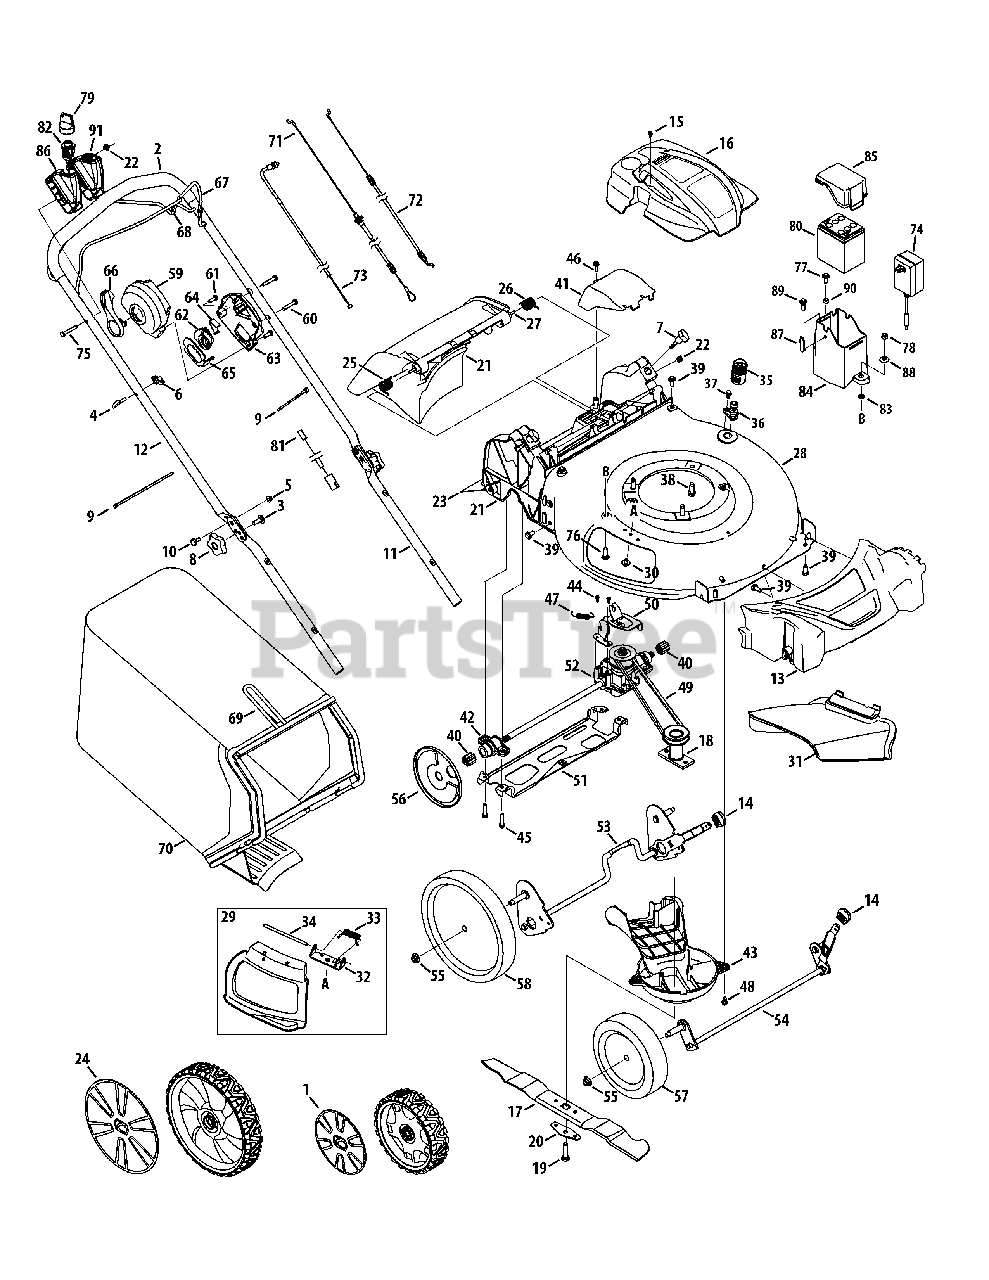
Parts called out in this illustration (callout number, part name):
1	Hubcap, 8"
3	Carriage Screw ,5/16-18
4	Rope Guide
5	Nut, Flange Lock, 1/4-20
7	Wing Nut
9	Cable Tie
10	Shdr. Screw, .375 x .126 x 1/4-20
11	Lower Handle
13	Front Cover
14	Adjustment Knob
15	Screw, HL, #12-16 x 1.00
16	Engine Shroud
17	Mulching Blade
18	Blade Adapter
19	Screw, 3/8-24 x 1.50
20	Blade Bell Support
21	Rear Discharge Door Assembly
22	Nut, Sq., 1/4-20
23	Trail Shield
24	Hubcap, 11"
25	Torsion Spring - RH
26	Torsion Spring - LH
29	Mulch Plug (Incl. 32-34)
31	Side Discharge Chute
32	Chute Deflector Bracket
33	Torsion Spring
35	Water Nozzle Adapter
36	Water Nozzle
37	Screw, Shldr., 1/4-20 x .50
38	Screw, tt, 3/8-16 x 1.00
39	Screw, 5/16-14 x .750
40	Spur Gear, 9T
41	Transmission Cover
42	Bearing Assembly
43	Engine Baffle
44	Screw, Hex Washer, .159 x .43
45	Screw, 1/4-15 x 1.25
46	Screw, 1/4-15 x .750
47	Exten. Spring, 2.675
48	Screw, Shldr., 1/4-20 x .50
50	Transmission Bracket
51	Rear Support Bracket
52	Transmission
53	Rear Axle Assembly
54	Front Axle Assembly
55	Flange Lock Nut, 3/8-16
56	Wheel Dust Cover
57	Front Wheel, 8 x2
58	Rear Wheel, 11 x 2
59	Control Housing Assembly
60	Screw, 1/4-15 x 1.50
61	Screw, 1/4-15 x .750
62	Speed Cable Actuater
63	Lower Control Housing
64	Shift Lever Spring
65	Cable Adjustment Plate
66	Speed Select Lever
67	Blade Control
68	Drive Control
69	Grass Catcher Frame
71	Speed Adjustment Cable
72	Control Cable
73	Speed Select Cable
74	Battery Charger
75	Hex Cap Screw, 1/4-20 x 1.75
76	Screw, 5/16-18 x 1.00
77	Screw, 5/16-14 x .750
78	Nut, 5/16-18, Hexlock
79	Key
80	Battery
81	Electric Start Harness
82	Key Switch
83	Nut, Spd.
84	Battery Housing
85	Battery Housing, Top
86	Switch Housing, RH
87	Seal
88	Washer, Bell, .340 x .872 x .060
89	Shoulder Screw, 5/16-14 x .972
90	Spacer, .340 x .460 x .246
91	Switch Housing, LH
